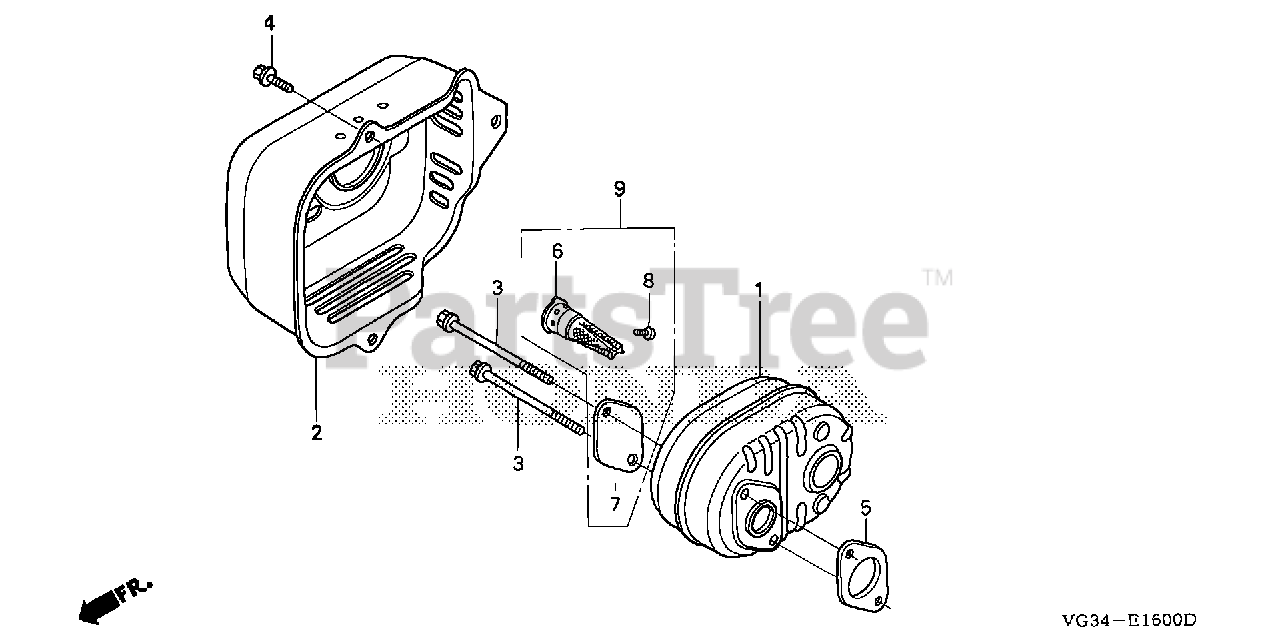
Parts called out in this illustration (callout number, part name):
2	PROTECTOR, MUFFLER (BLACK)
3	BOLT, FLANGE (6X79) (CT200)
4	BOLT, FLANGE (6X12) (CT200)
5	GASKET, MUFFLER
6	ARRESTER, SPARK (OPTIONAL)
7	PLATE, ARRESTER NUMBER (TO INSTALL OPTIONAL SPARK ARRESTER)
8	SCREW, TAPPING (4X6) (TO INSTALL OPTIONAL SPARK ARRESTER)
9	ARRESTER KIT, SPARK
